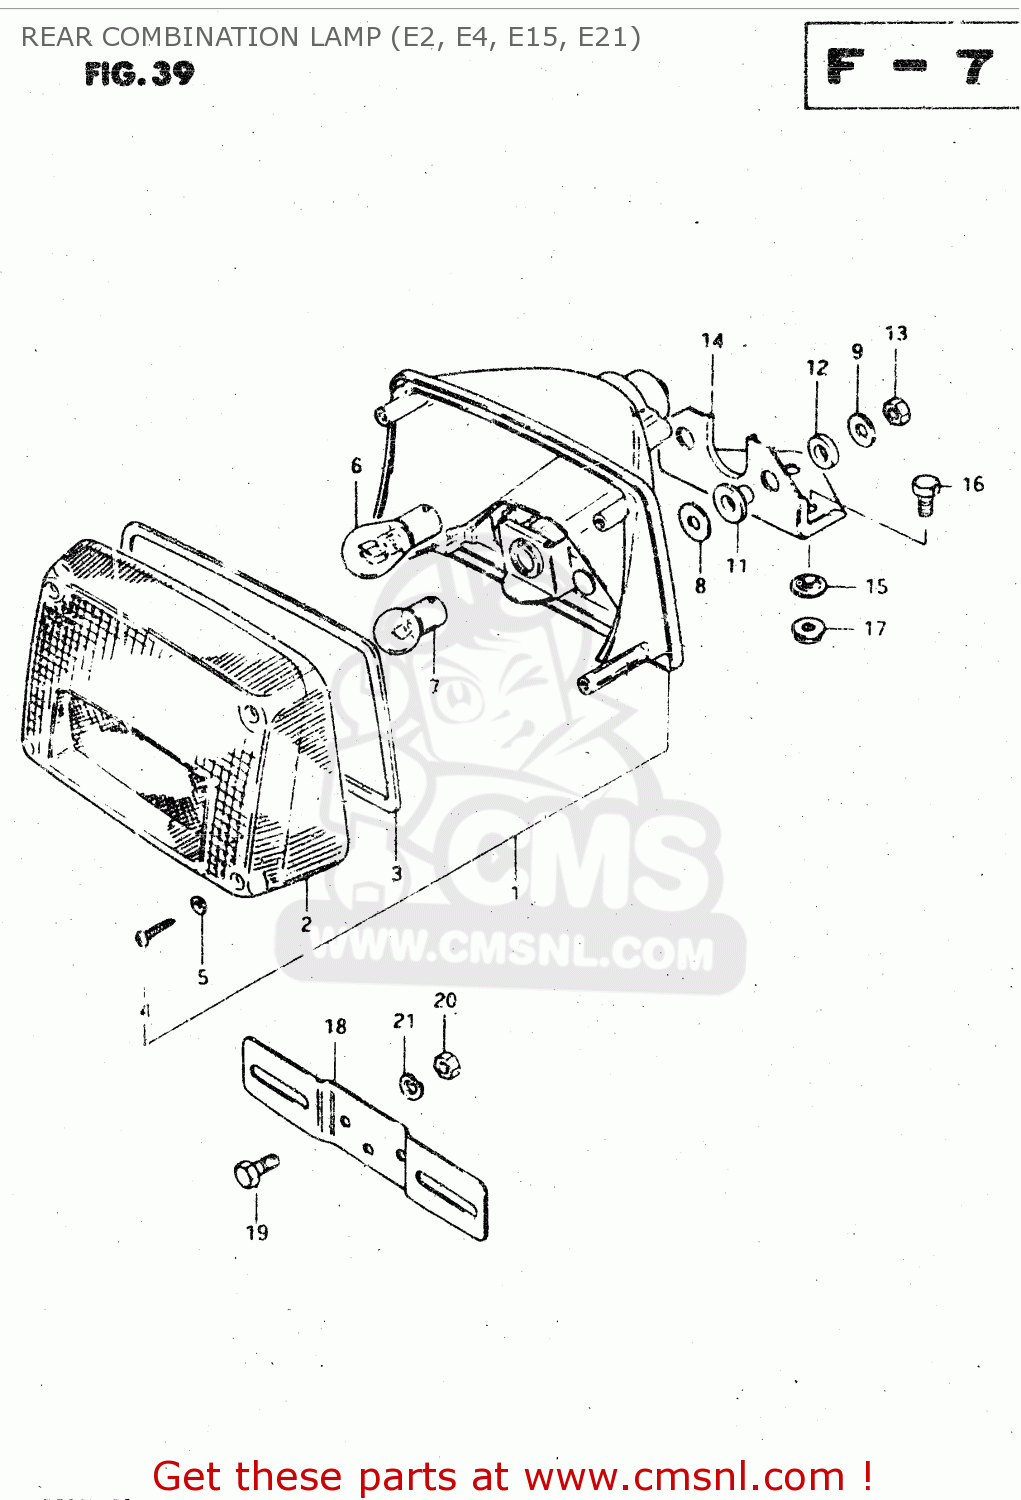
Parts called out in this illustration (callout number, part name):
1	LAMP ASSY, TAIL
2	LENS,RR COMBI
3	GASKET (NAS)
4	SCREW,REAR COMBINATION LAMP
5	GASKET (NAS)
6	BULB(12V21/5W)
7	BULB
8	WASHER
9	WASHER(6,5X22X1.6)
10	SPACER(6.1X9X7.5)
11	CUSHION
12	CUSHION
13	NUT 6MM
14	BRACKET,RR COMBINATION LAMP
15	WASHER
16	BOLT, UPPER
17	NUT 6MM
18	PLATE,RR LICENSE
19	BOLT
20	NUT
21	LOCK WASHER
